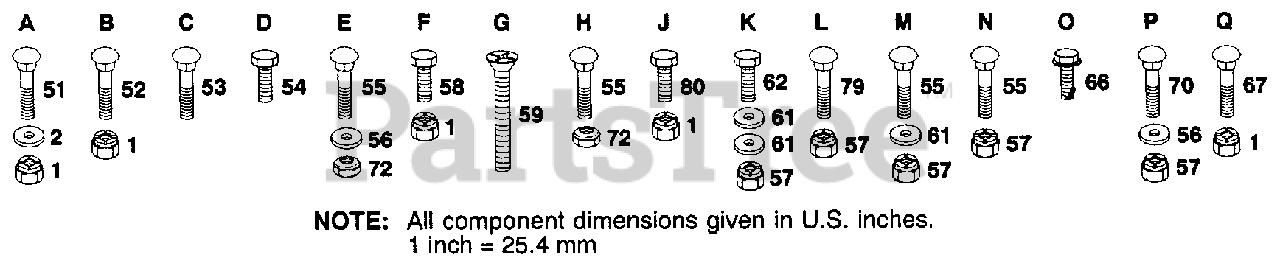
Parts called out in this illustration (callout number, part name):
2	WASHER
51	BOLT
53	BOLT
55	BOLT
56	WASHER
58	BOLT - HEX 3/8 - 16 X 3
59	SCREW YT
61	WASHER M
62	BOLT
66	SCREW
67	BOLT
79	BOLT
80	BOLT
